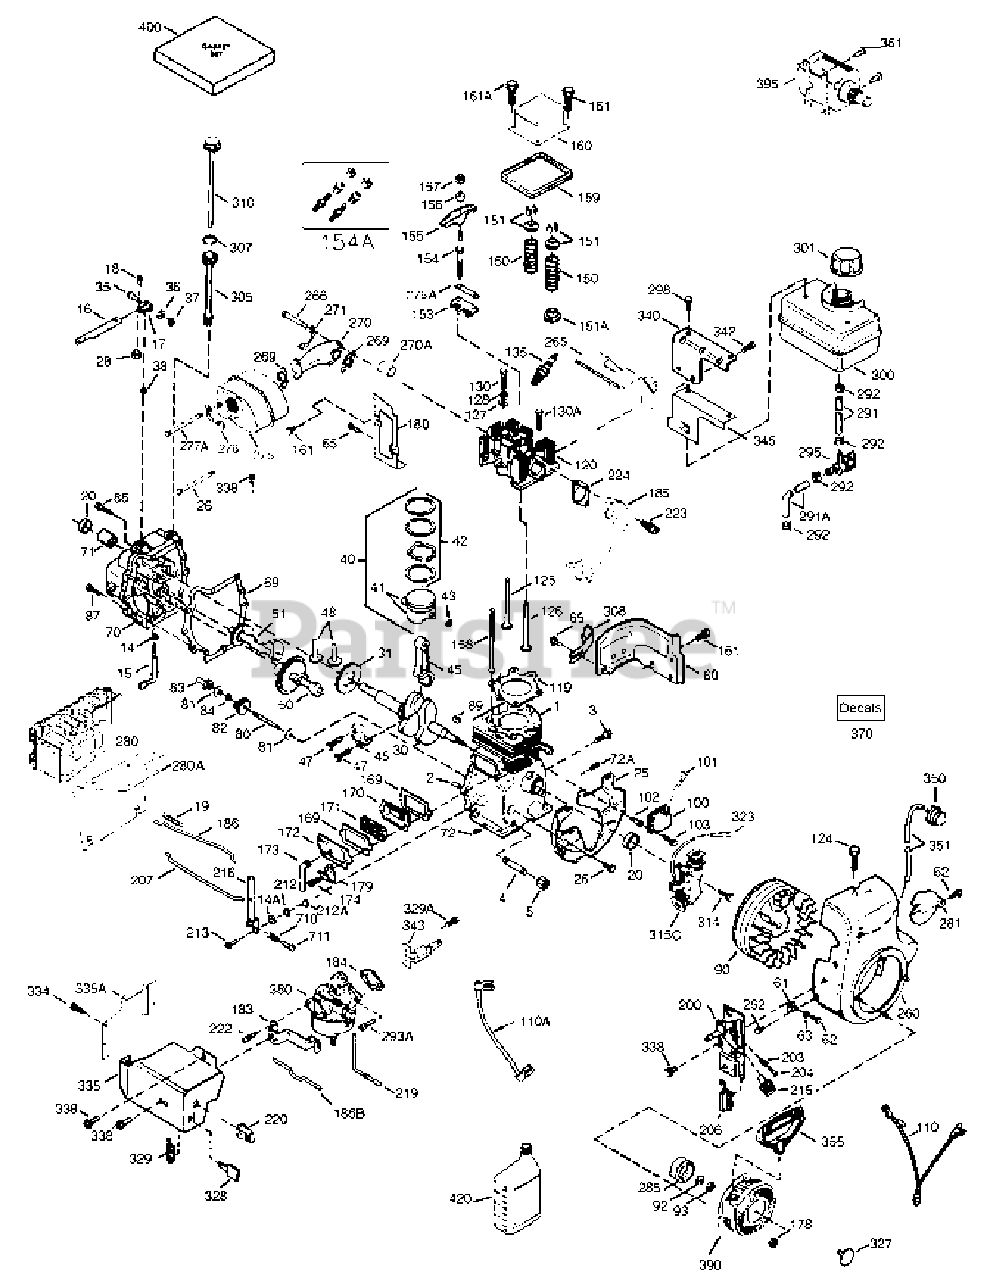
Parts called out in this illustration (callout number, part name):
1	Cylinder (Incl. 2, 20 72 & 80)
2	Dowel Pin
3	Screw, 1/4-20 x 1/2"
4	Oil Drain Extension
5	Extension Cap, 1/4-18 NPT
14	Flat washer
15	Governor Rod (Incl.14 & 38)
16	Governor Lever (Incl. 212A)
17	Governor Lever Clamp
18	Screw, T-15, 8-32 x 7/16"
19	Extension Spring
25	Blower Housing Baffle (Incl. 325)
26	Screw 1/4-20 x 19/32"
28	Lock Nut, 8-32
30	Crankshaft
31	Counterbalance Gear
35	Screw, 10-32 x 3/4"
36	Lock Washer #8
37	Lock Nut, 10-32
38	Retaining Ring
40	Piston, Pin & Ring Set (Std) (Incl. 41, 42 &43)
40	Piston, Pin & Ring Set (.010" OS)(Incl. 41, 42 & 43)
42	Ring Set (Std.)(3-5/16"
42	Ring Set (.010" OS)
43	Piston Pin Retaining Ring
45	Connecting Rod Assembly (Incl. 47& 49)
47	Connecting Rod Bolt (1/4-20 x 1- 5/16")
48	Valve Lifter
50	Camshaft (MCR)
51	Counterbalance Weight
60	Blower Housing Extension
65	Screw, 10-24 x 9/16"
69	Cylinder Cover Gasket
70	Cylinder Cover (Incl. 14, 15, 20, 38)
71	Crankshaft Bushing
80	Governor Shaft
82	Governor Gear Assembly
83	Governor Spool
84	Retaining Ring
86	Screw 1/4-20 x 1-3/16"
87	Screw, 1/4-20 x 1-11/16"
89	Flywheel Key
90	Flywheel (3 amp, w/ring gear)
92	Belleville Washer
93	Flywheel Nut (5/8-18)
100	Solid State Ignition (Incl. 101)
101	Spark Plug Cover
102	Solid State Mounting Stud
103	Screw, T-15, 10-24
110	Ground Wire
110A	Ground Wire(10.50" with male & female flag terminals)
119	Cylinder Head Gasket
120	Cylinder Head(Incl. 151A & 270A)
125	Exhaust Valve (Std)
125	Exhaust Valve(1/32" OS)
126	Intake Valve (Std.)
126	Intake Valve (1/32" OS)
127	Flat washer
128	Belleville Washer
130	Screw, 5/16-18 x 2-1/2"
135	Resistor Spark Plug (RN4C)
149A	Intake Valve Seal
150	Valve Spring
151	Valve Spring Keeper
153	Push Rod Guide
154	Rocker Arm Stud
155	Rocker Arm
156	Rocker Arm Bearing
157A	Jam Nut, 5/16-24
159	Rocker Arm Cover Gasket
160	Rocker Arm Cover
161	Screw, T-30, 1/4-20 x1/2"
161A	Valve Cover Mounting Stud
169	Valve Cover Gasket
170	Breather Body
171	Breather Element
172	Valve Cover
173	Breather Tube
174	Screw, 10-24 x1/2"
178	Nut & Lock Washer 1/4-28
180	Blower Housing Extension
183	Choke bracket
184	Carburetor-to-Intake Pipe Gasket
185	Intake Pipe
186	Governor Link
186B	Choke Spring
200	Manual Control Bracket (Incl. 203, 204 & 206)
203	Compression Spring
204	Screw, T-10, 5-40 x 7/16"
207	Throttle Link
212	Bushing (Incl. 14A & 213)
213	Screw, 10-32 x 5/8"
215	Control Knob
216	R.P.M. Adjusting Lever
219	Choke Rod
220	Control Knob
223	Screw, T-30, 5/16-18 x 7/8"
224	Intake Pipe Gasket
238	Screw, 10-32 x 1/2"
260	Blower Housing
262	Screw, 5/16-18 x 9/16"
265	Cylinder Head Cover
266	Screw, 5/16-18 x 1-9/32"
269	Exhaust Manifold Gasket
270	Exhaust Manifold
270A	Exhaust Port Liner
271	Locking Plate (Manifold)
276	Locking Plate
277A	Screw, 5/16-18 x 4-1/2"
280A	Heat Shield
285	Starter Cup
290	Fuel Line (32.0" Length)
292	Fuel Line Clamp
293A	Screw, T-30, 1/4-20 x 27-32"
298	Screw, 1/4-15 x 3/4"
300	Fuel Tank (Incl. 292 & 301)
301	Fuel Cap (Red Plastic) (1-1/2" I.D.)
305	Oil Fill Tube
308	Fill Tube Clip
309	Screw, 10-32 x 5/16"
314	Screw, 1/4-20 x 3/4"
328	Ignition Key
329A	Screw, 8-32 x 23/64"
335	Carburetor Cover
335A	Carburetor Cover
338	Screw, 10-32 x 1/2"
342A	Screw, 5/16-18 x 7/8"
343	Key Switch Bracket (Incl. 329A)
345	Heat Baffle
350	Primer Assembly
351	Primer Line
355	Starter Handle (Mitten Grip)
361	Screw, T-30, 1/4-20 x 15/32"
370	Decal - Primer - International Symbol
370	Warning Decal
370	Decal - Tecumseh Logo for Top of Recoil Starter
370	Warning Decal (Bilingual)
370	Decal - Speed Control, Choke, & Key
380	Carburetor (Incl. 184)
390	Rewind Starter (Refer to Division 5, Section c Page 43 for bre
400	Gasket Set
420	SAE 5W30 4-Cycle Engine Oil (Quart) (Winter)
704	Screw, 1/4-20 x 5/8"
710	Compression Spring
711	Screw, T-10, 6-32 x 41/64"
999	Winter Maintenance kit
